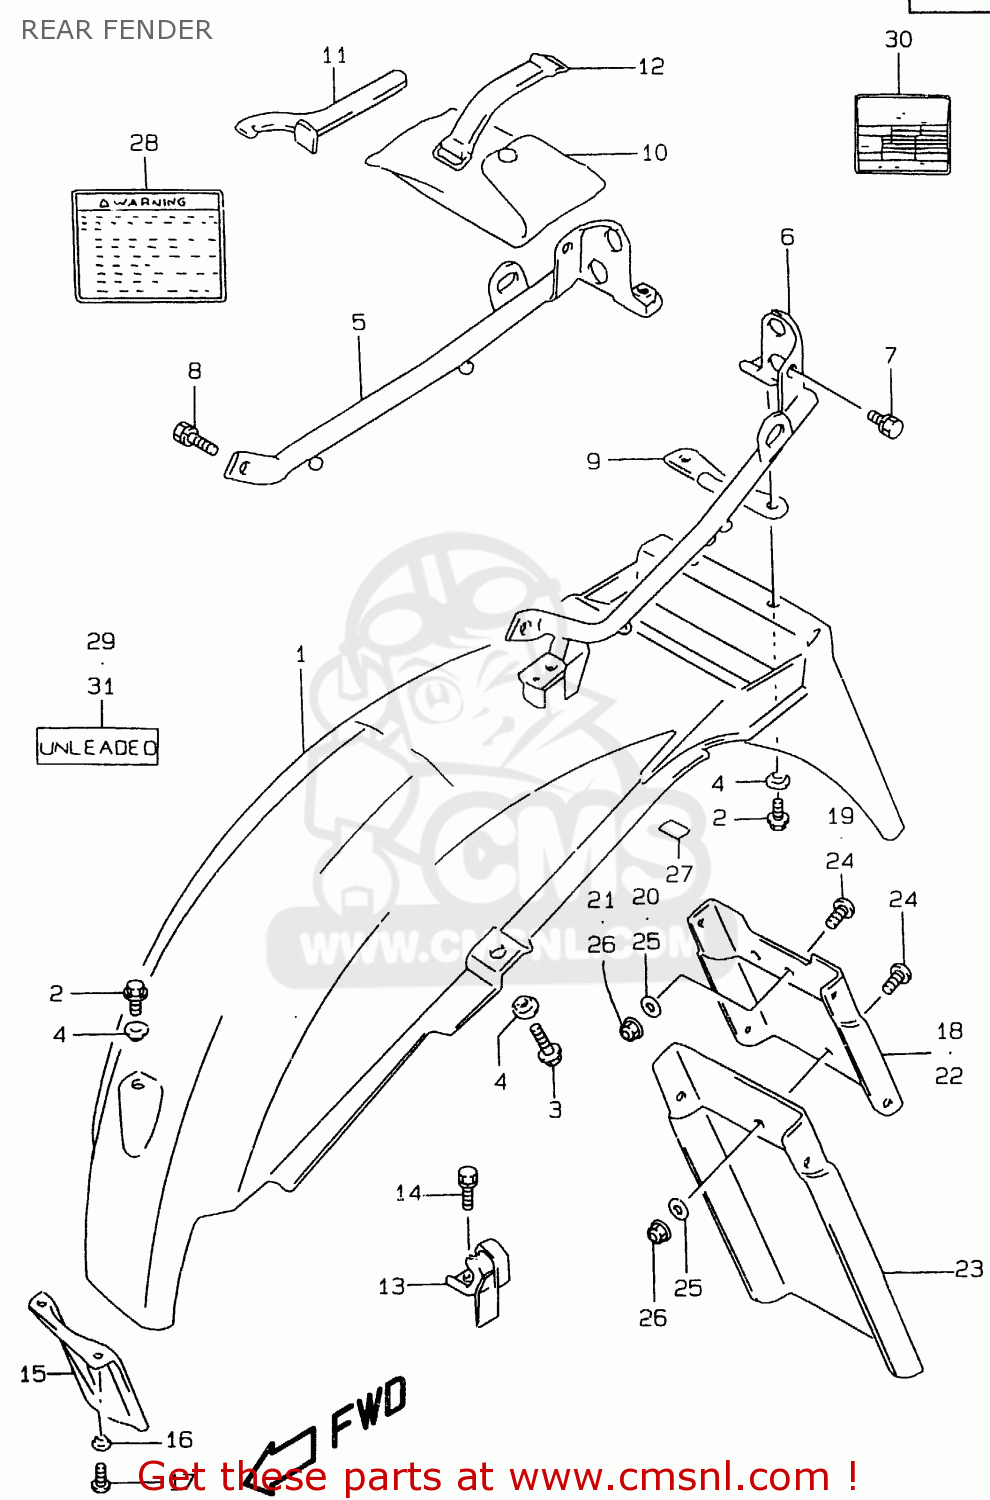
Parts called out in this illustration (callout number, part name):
1	BODY,RR FENDER
2	BOLT
3	BOLT
4	WASHER
5	BRACE,RR FENDER,R
6	BRACE,RR FENDER,L
7	BOLT
8	BOLT
9	PLATE,TOOL HOLDER
10	TOOL ASSY
11	CLAMP
12	BAND
13	HOLDER,HELMET
14	BOLT
15	GUARD,RR UNIT MUD
16	WASHER
17	SCREW
18	EXTENSION,RR FENDER
19	SCREW
20	WASHER(6.5X16X1.2)
21	NUT 6MM
22	EXTENSION,RR FENDER
23	MUDGUARD,RR FENDER
24	SCREW
25	WASHER(6.5X16X1.2)
26	NUT 6MM
27	TAPE,RR FENDER
28	LABEL,WARNING
29	LABEL,CAUTION
30	LABEL,TIRE AIR PRESSURE
31	LABEL,FUEL CAUTION
32	O.M. GS500E V
